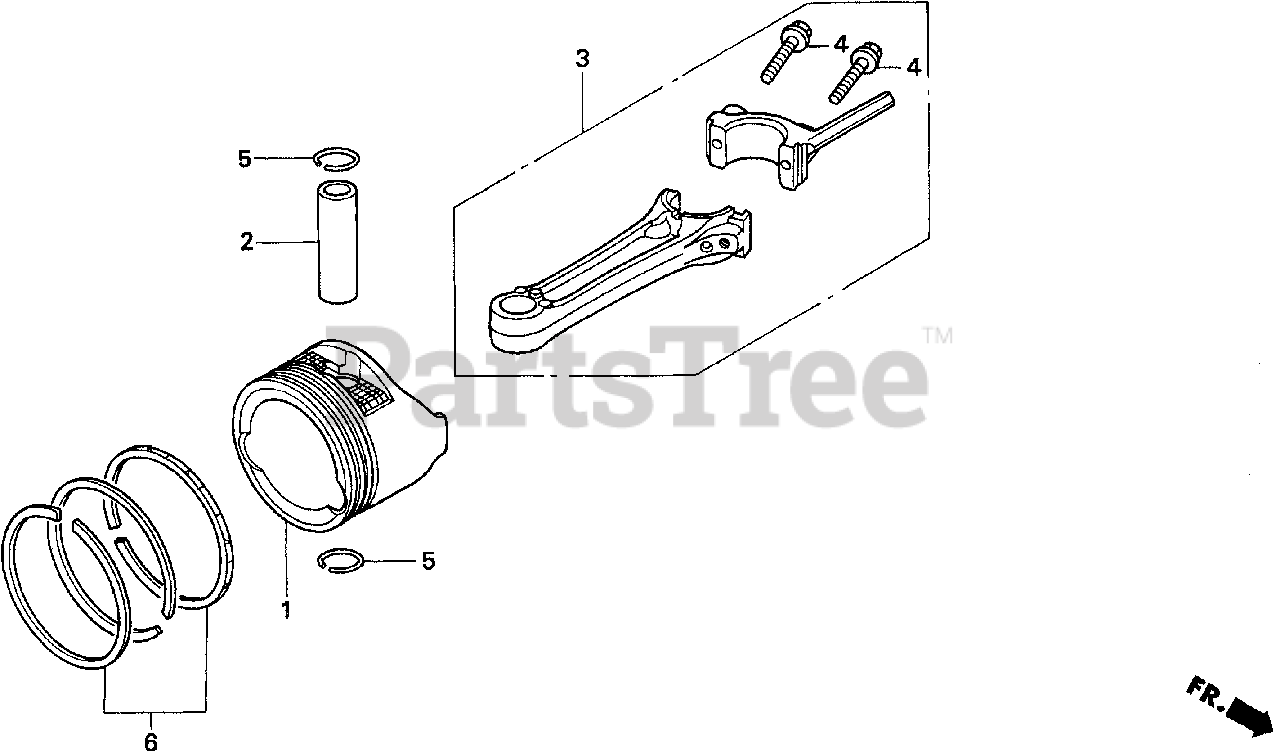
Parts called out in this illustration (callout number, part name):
1	PISTON
2	PIN, PISTON
3	ROD ASSY., CONNECTING
4	BOLT, CONNECTING ROD
5	CLIP, PISTON PIN (13MM)
6	RING SET, PISTON (TEIKOKU)
